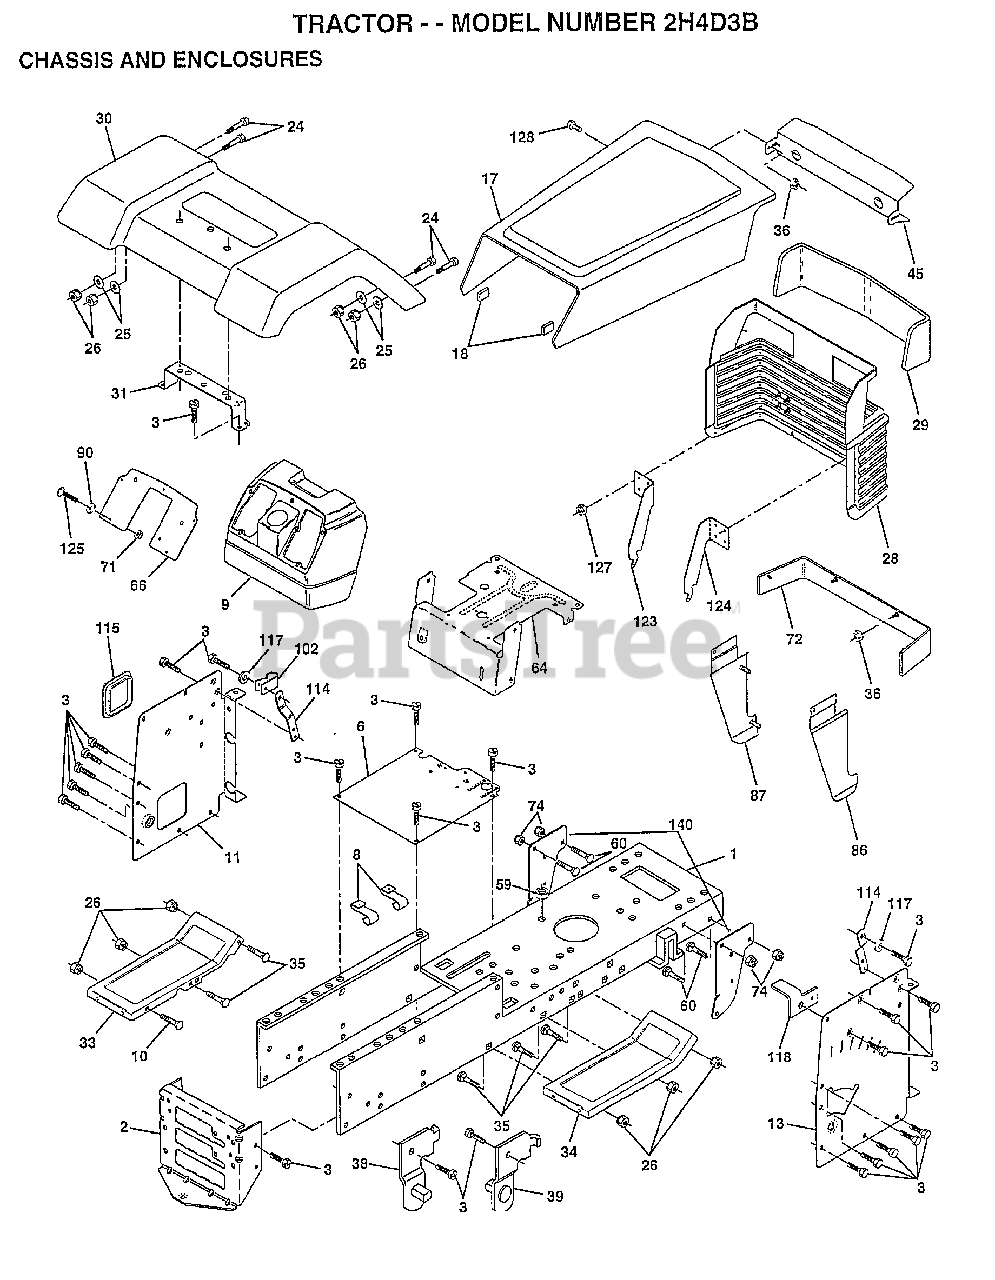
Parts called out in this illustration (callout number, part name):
1	CHASSIS WLDMT 11G
3	SCREW
8	"CLIP,INSULATOR"
9	DASH.PLASTIC.BLK
11	PANEL.DASH.LH.
13	PANEL.DASH.RH.NOT
17	HOOD.ASM.YTGT.PNT
24	BOLT
25	WASHER
26	NUT
28	GRILLE ASM WELD
30	FENDER
31	BRKT FENDER
33	FOOTREST LH
34	FOOTREST RH
35	BOLT
36	PAL NUT LT
38	BRACKET ASM LH
39	BRACKET ASM RH
64	DASH.LOWER.LT
66	PLATE DASH SILKSC
71	NUT HXKEP 1/4X20
72	STRAP GRILLE 505
86	PANEL.SIDE.RH.ASM
87	PANEL.SIDE.LH.ASN
90	WASHER PM
102	CLIP T
114	BRACKET.SUPT.DASH
115	WASHER
117	WASHER.SERRATED.
118	BRACKET.CLUTCH.MC
123	BRACKET.PICK.LH.
124	BRACKET.PICK.RH.
125	SCREW
127	PAL NUT
128	SCREW SPECIAL
